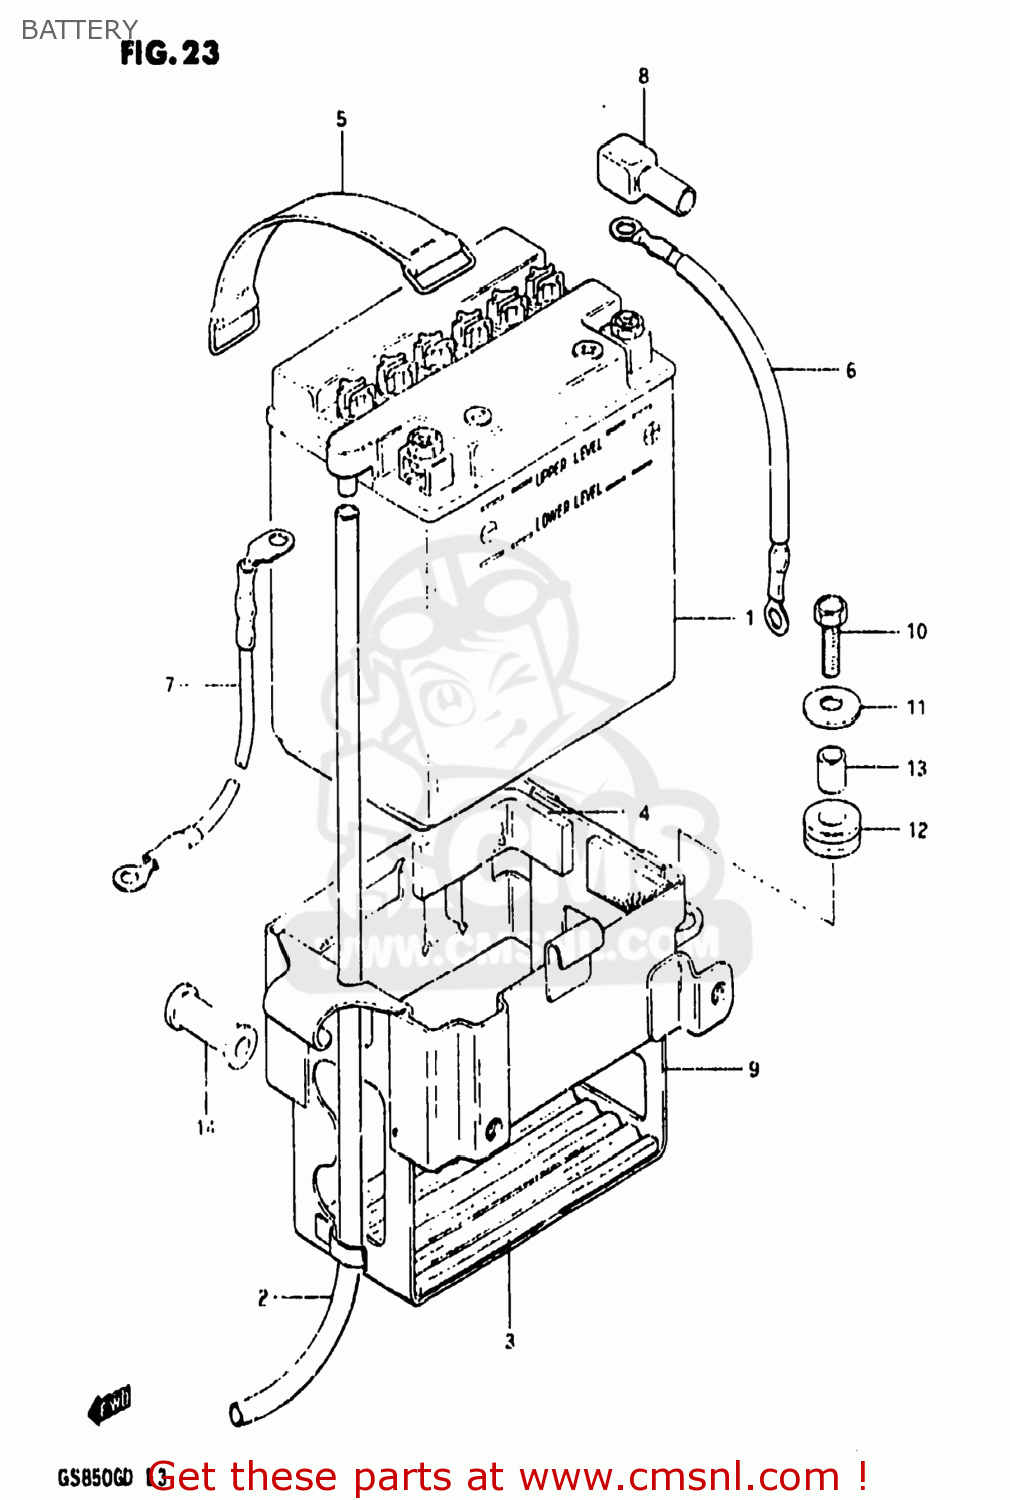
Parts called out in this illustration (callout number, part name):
1	BATTERY ASSY (12V)
2	HOSE,BATTERY EXHAUST
3	PROTECTOR,BATTERY
4	PROTECTOR(20X90)X4
5	BAND
6	WIRE,BATTERY PLUS
7	LEAD WIRE,BATTERY(-)
8	CAP,TERMINAL
9	HOLDER,BATTERY
10	BOLT, UPPER
11	WASHER(6,5X22X1.6)
12	CUSHION
13	SPACER(6.2X8.3X5.7)
14	CUSHION
